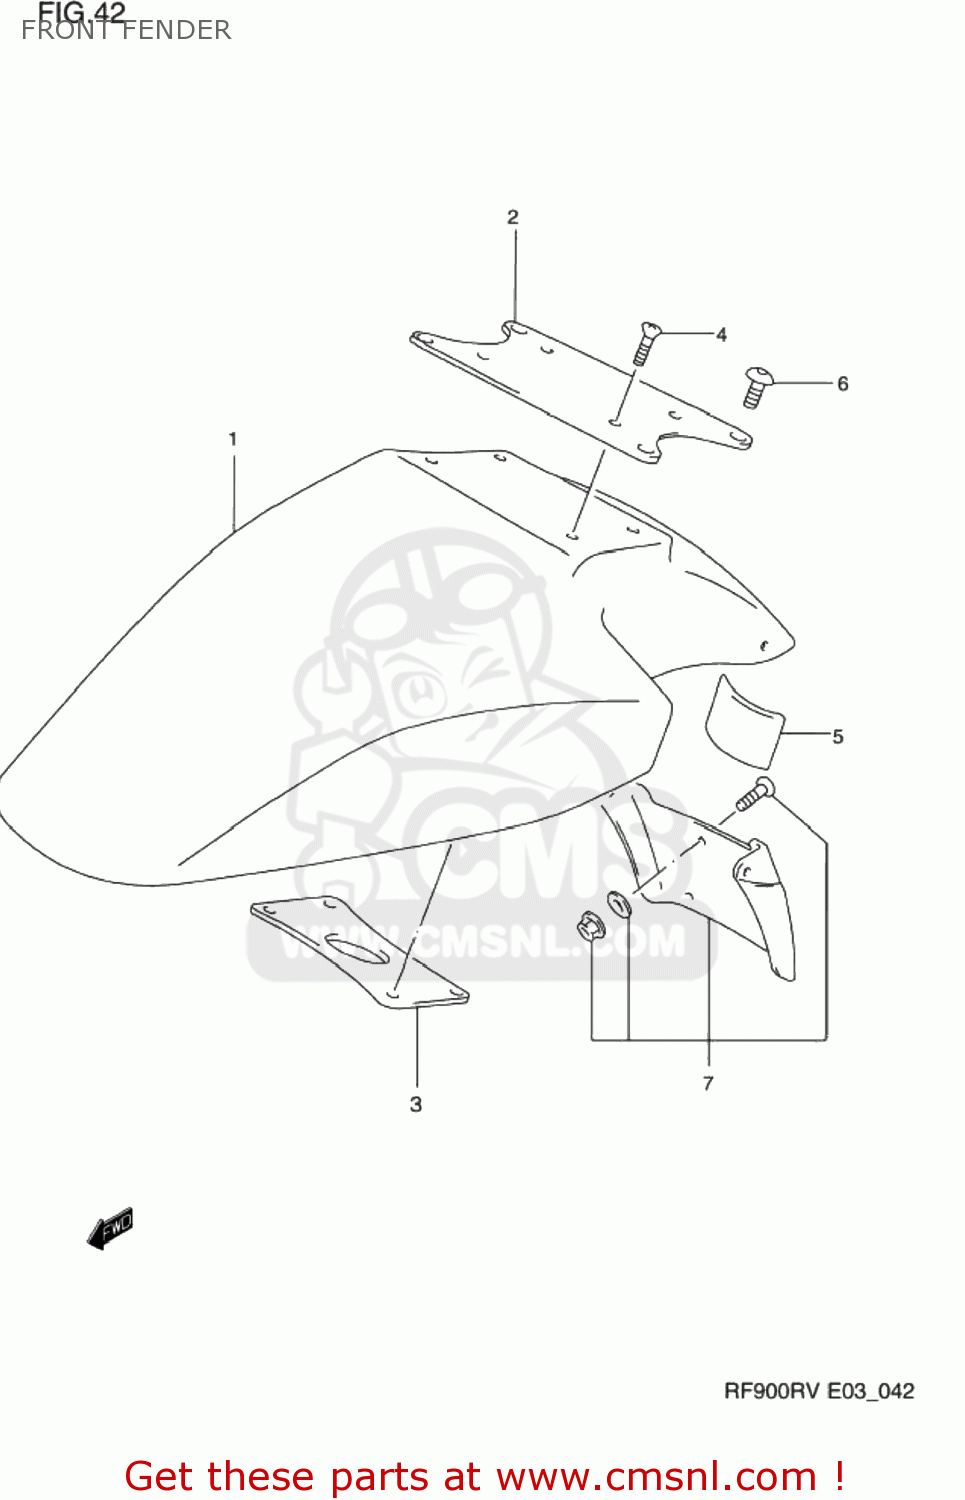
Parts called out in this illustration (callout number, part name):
1	FENDER,FR
2	BRACE,FR FENDER
3	BRACE,FR FENDER INNER
4	SCREW(5X18)
5	CUSHION,FR FENDER
6	SCREW(8X16)
7	MUDGUARD SET,FR FENDER
